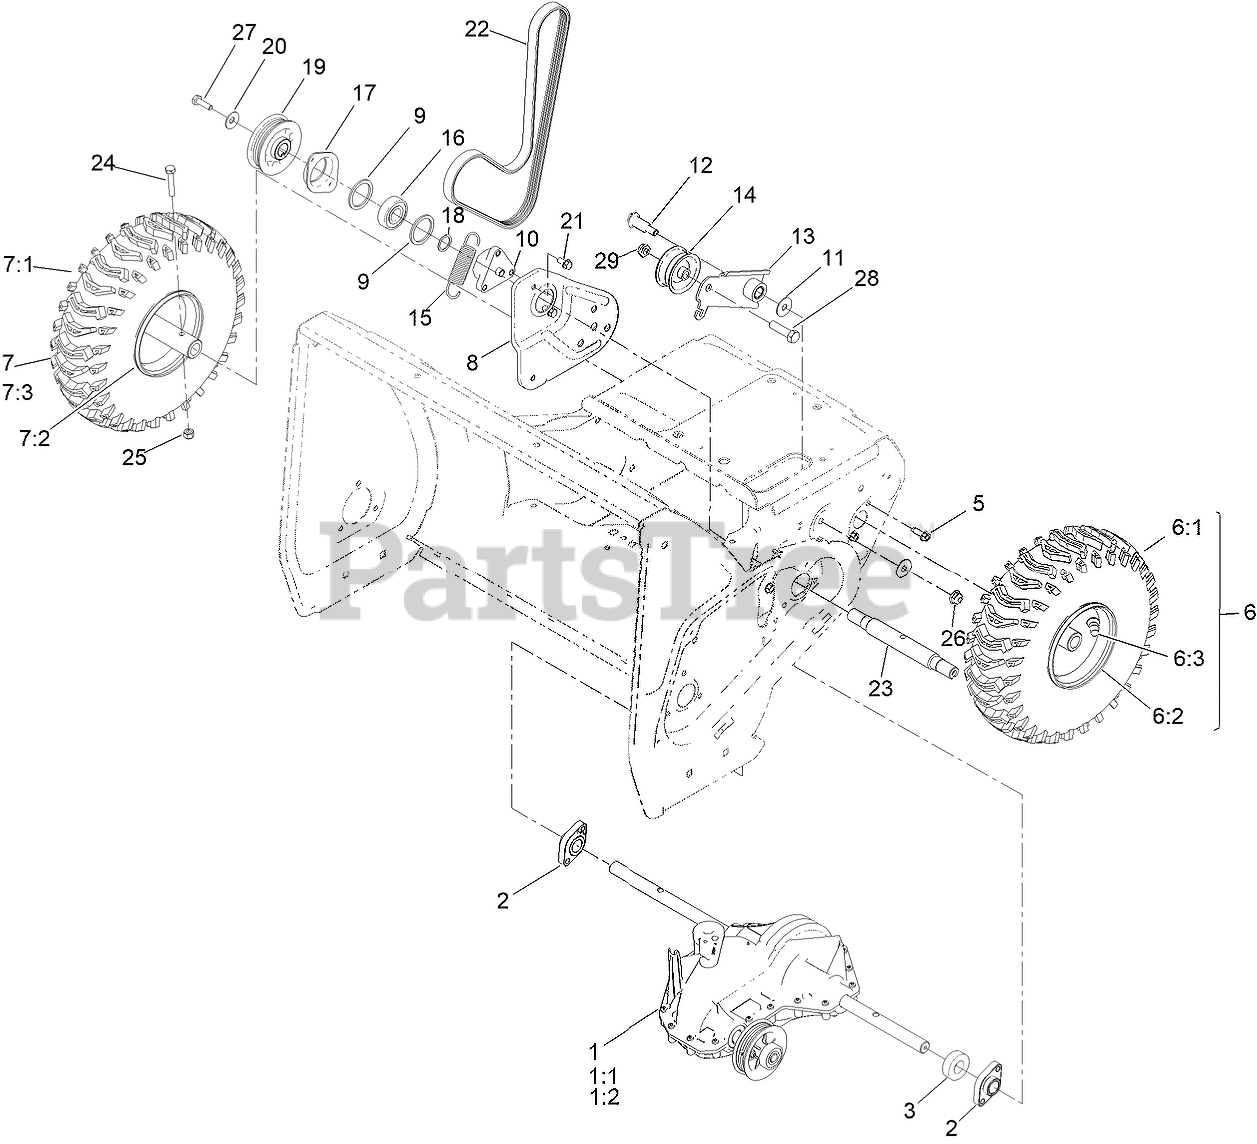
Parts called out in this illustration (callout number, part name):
1	TRANSMISSION
1:1	PULLEY REPAIR KIT
1:2	PLUG-OIL
2	BEARING-AXLE
3	SPACER-AXLE
5	SCREW-HWHTF
6	LH WHEEL AND TIRE ASM
7	RH WHEEL AND TIRE ASM
8	PLATE-SUPPORT, JACKSHAFT
9	WASHER-RUBBER
10	SUPPORT-BEARING
11	WASHER
12	BOLT-SHOULDER, HHF
13	IDLER-TRACTION
14	PULLEY-IDLER, FLAT
15	SPRING-EXTENSION
16	BEARING-BALL
17	RETAINER-BEARING
18	WASHER-THRUST
19	PULLEY-JACKSHAFT
20	WASHER-BELLEVILLE
21	SCREW-HWH
22	BELT-POLY V
23	JACKSHAFT
24	SCREW-HH
25	NUT-HEX
26	NUT-HF
27	SCREW-HH,LOCK
28	SCREW-HH
29	NUT-HEX
